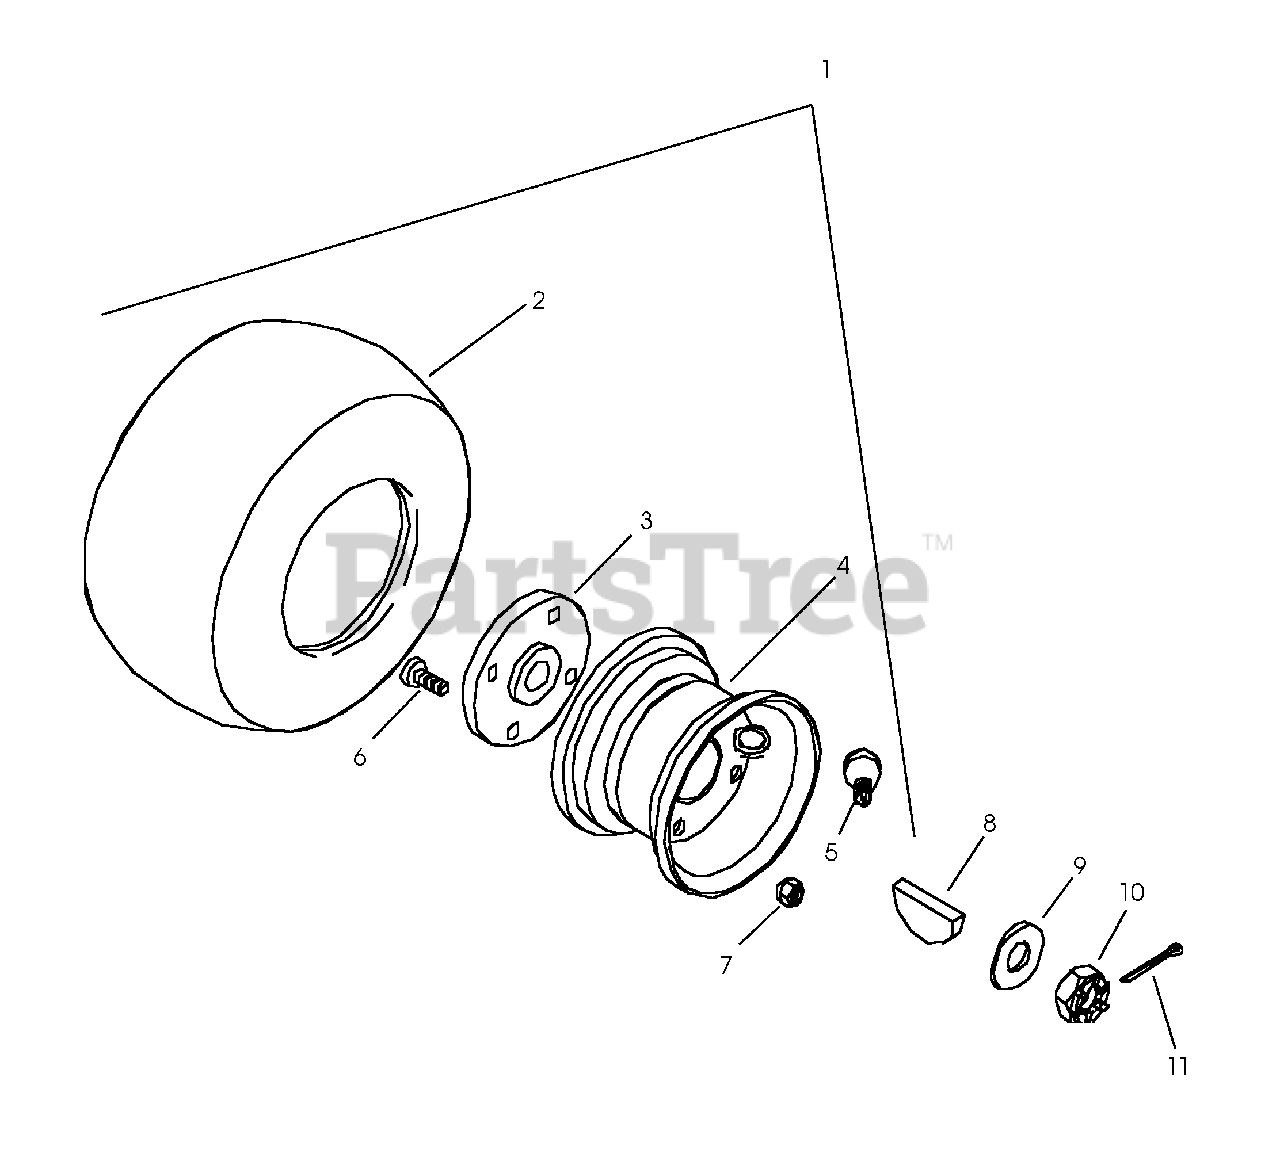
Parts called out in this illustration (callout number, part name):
1	Tire/Wheel Assembly
2	Tire 18 x 8.50-8
3	Assembly-Hub
4	Assembly-Rim
5	Valve Stem Assembly
6	Bolt .50-20 x 1.25
7	Nut-Hex .50-20
8	Key-Woodruff .188 x .75 x .313
9	Washer-Flat-Steel .781 x 1.50 x .060
10	Nut-Hex 3/4-28
11	Pin-Cotter .09 x 1.00
